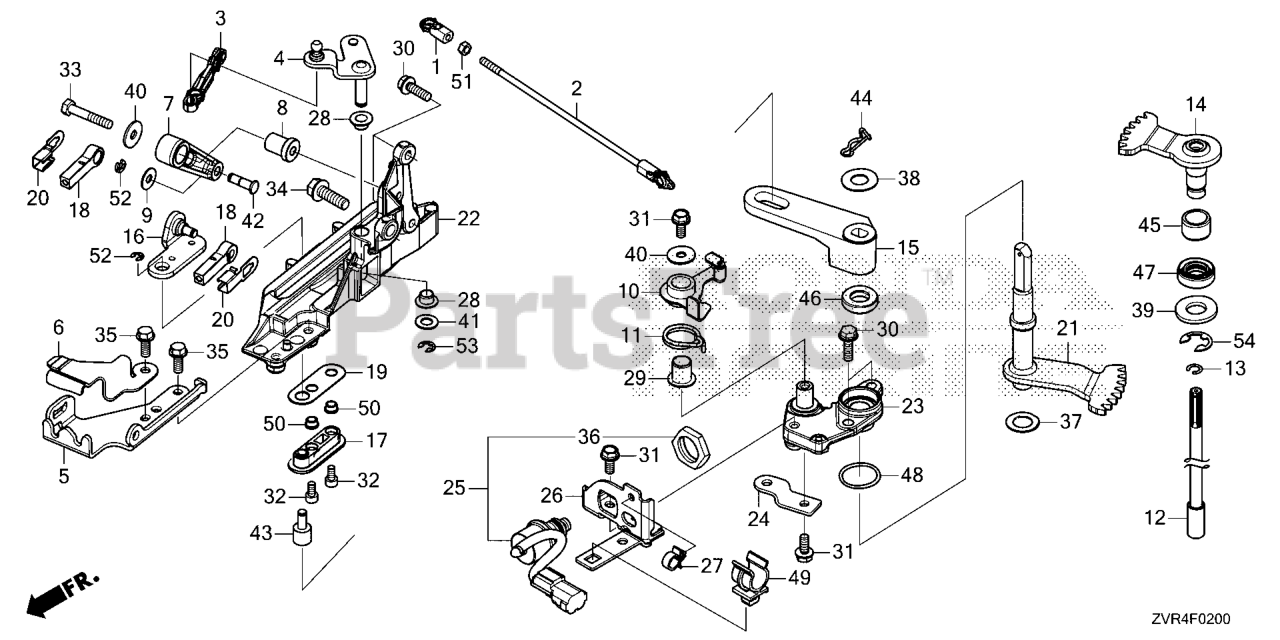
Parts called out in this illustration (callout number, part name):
1	LINKAGE, PIVOT
2	ROD, THROTTLE
3	LINK, THROTTLE
4	PLATE, THROTTLE
6	CVR, REMOTE CONTROL
7	ARM, THROTTLE
8	SHAFT, THROTTLE ARM
9	WASHER, PIVOT
10	ARM, CLICK
11	SPRING, CLICK
12	ROD A, SHIFT (L)
13	RING, STOPPER
14	SHAFT A, SHIFT
15	ARM, SHIFT
16	PLATE, SHIFT PIVOT
17	PIVOT, SHIFT SLIDE
18	PIVOT, SHIFT
19	PLATE, SHIFT SLIDE
20	PLATE, LOCK
21	SHAFT B, SHIFT
22	BRACKET, SHIFT LINK
23	HOLDER, SEAL *NH8*
24	BRACKET, CABLE A
25	SWITCH ASSY., NEUTRAL
26	BRACKET, NEUTRAL
27	CLIP, BRAKE PIPE (A) (FOR NEUTRAL SWITCH)
28	BUSH A, COVER LOCK
29	BUSH, BLADE BRAKE
30	BOLT, FLANGE (6X20)
31	BOLT, FLANGE (6X14)
32	BOLT, SOCKET (5X10)
33	BOLT, HEX. (6X35)
34	BOLT, FLANGE (8X25)
35	BOLT, FLANGE (6X16) (SUS)
36	NUT, HEX. (20MM) Use up to Frame SN 1300359.
37	WASHER B, THRUST (14MM)
38	WASHER, PLAIN (12MM)
40	WASHER, PLAIN (6MM)
41	WASHER, PLAIN (8MM) Use from Frame SN 4800713.
44	PIN, SNAP (12MM)
45	RING (INNER) (15X20X13)
46	OIL SEAL (14X26X6)
47	SEAL, WATER (14X26X8)
48	O-RING (25X2.4) (NOK)
49	HOLDER, DRAIN TUBE
50	COLLAR (5.5X8X4.5)
51	NUT, HEX. (5MM)
52	E-RING (4MM)
53	E-RING (6MM)
54	E-RING (12MM)
